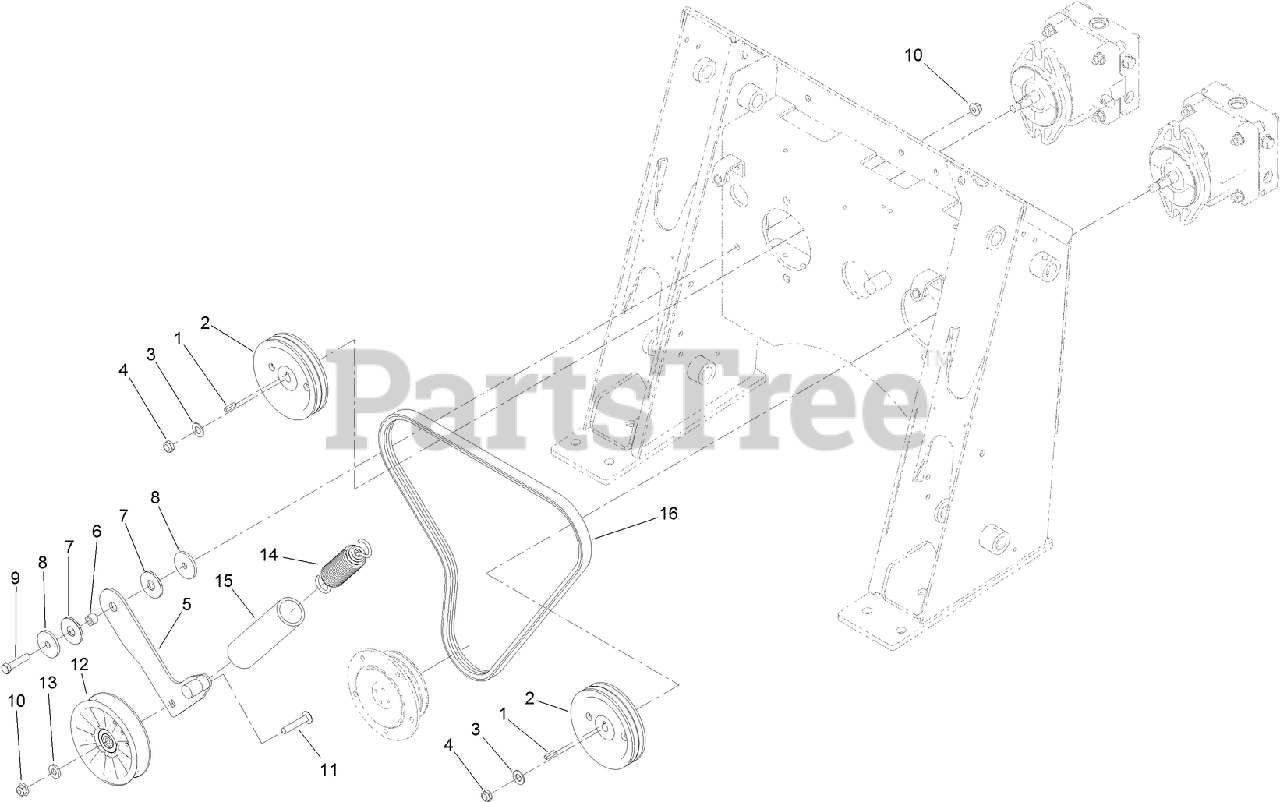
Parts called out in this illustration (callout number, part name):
2	PULLEY-3V
3	WASHER-FLAT
4	NUT-LOCK, NI
5	IDLER ARM ASM
6	SPACER
7	WASHER-FRICTION, COMPOSITE
8	WASHER-PLAIN
9	SCREW-HH
10	NUT-HF, NI
11	BOLT-CARRIAGE
12	PULLEY-IDLER
13	SPACER
14	SPRING-EXTENSION
15	RETAINER-SPRING
16	V-BELT
